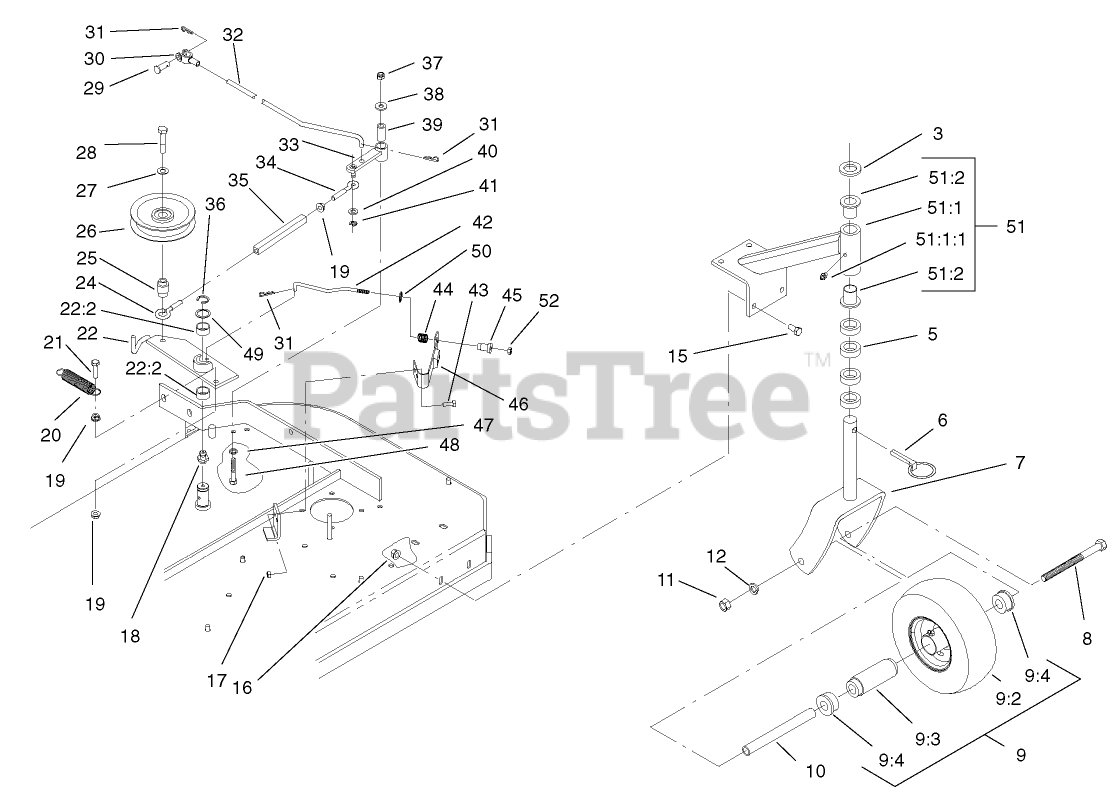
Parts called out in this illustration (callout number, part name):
3	WASHER-FLAT
5	SPACER-CASTER
7	FORK
8	SCREW-HH
9	WHEEL AND TIRE ASM
9:3	BEARING
9:4	BUSHING
10	SPACER
11	NUT-HH
12	WASHER-LOCK
15	SCREW-HH
16	NUT-HHF, WHIZ
17	NUT-LOCK, NI
18	FITTING-GREASE
19	NUT-HF
20	SPRING-EXTENSION
21	SCREW-HH
22	ASM,IDLER ARM/BUSHINGS
22:2	SLEEVE-BEARING
24	EYEBOLT-THREAD, LH
25	BUSHING-ENGAGEMENT
26	PULLEY-IDLER
27	WASHER-BELLEVILLE
28	SCREW-HH
29	PIN-CLEVIS
30	YOKE-ADJUSTABLE
31	PIN-COTTER
32	ARM-ASSIST, LINKAGE
33	ARM-ASSIST
34	EYEBOLT-THREAD, RH
35	BODY-TURNBUCKLE
36	RING-RETAINING, EXT
37	NUT-LOCK, NI
38	WASHER-FLAT
39	TUBE-PIVOT
40	WASHER-PLAIN
41	RING-RETAINING, EXT
42	ROD-BRAKE
43	SCREW-HH
44	SPRING-COMPRESSION
45	SPACER-FLANGED
46	PAD AND SPRING ASM
47	WASHER-SPRING
48	SCREW-HH
49	WASHER-SPINDLE
50	RING-PUSH ON
51	SUPPORT ASM
51:1	SUPPORT-CASTER
51:1:1	FITTING-GREASE
51:2	BEARING-FLANGED
52	NUT-LOCK, NI
